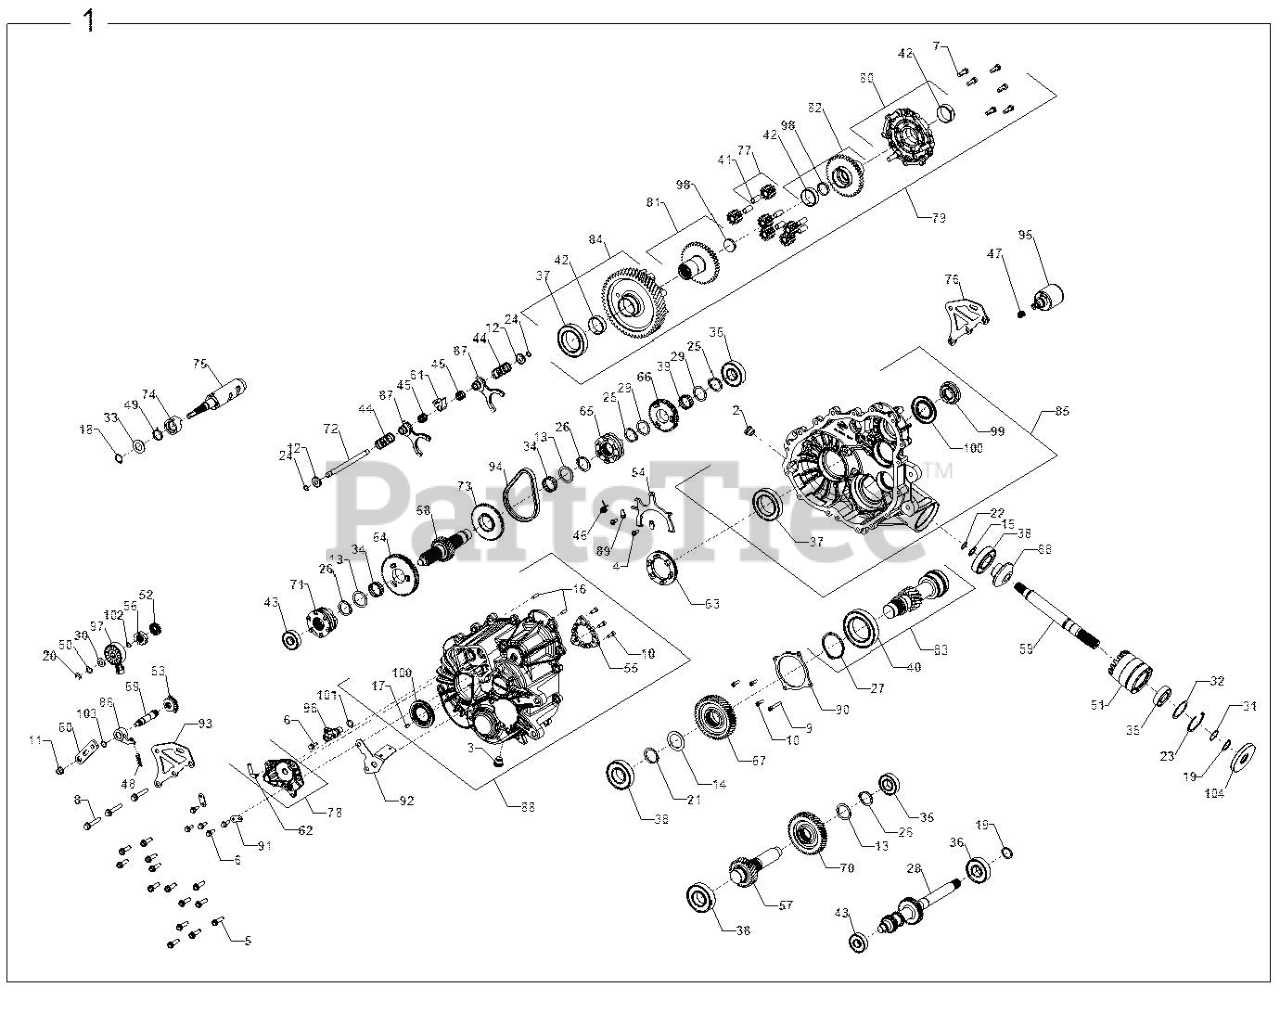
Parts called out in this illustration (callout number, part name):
1	ASM-GEARCASE,570,RGR
2	PLUG-SKT HD 1SO 6149,M18 X 1.5
3	PLUG-SOCKET HEAD W/MAG,M18X1.5
4	SCREW, TORX PAN HD M6 X 1 X 16
5	SCREW-HEXFLANGEHEAD,M8X1.25X30
7	SCREW-CAP HH,M8 X 1.25 X 20
9	SCR-M6X1.0X40,SOC/CAP(105344)
10	SCR-SCKT HD,CP,M6X1X18(105355)
11	NUT-M8X1.25,HXFLG,NYLN(110093)
12	WASHER-CUP
16	PIN, DOWEL, 6 X 20
17	SPRING-SLOTTED PIN,6MM
18	RING, RETAINING BASIC EXTERNAL
19	RING, SNAP
20	RING-RETAINING
21	RING,RETAINING
22	RING,RETAINING,EXTERNAL SHR-66
23	RING,RETAININGBASICINTRNL2.047
24	RING-RETAINING
25	RING,RETAINING
26	RING, RETAINING, EXTERNAL
27	RING, RETAINING
28	SHAFT-PINNION,INPUT,BOSS,LW
29	WASHER,THRUST
30	WASHER,THRUST,.446X.88X.025
31	SHIM 1.180 X .995
32	SHIM 2.040 OD X 1.630 ID
33	SPACER, 19.4 X 34 X 2
34	BEARING,NEEDLE
37	BEARING, BALL
38	BEARING-BALL
39	BEARING,NEEDLE
40	BEARING, BALL
41	BEARING,PLAIN,10X12X25
42	PLAIN,BEARING 40X44X15
43	BEARING, BALL
44	SPRING-COMPRESSION
45	SPRING-COMPRESSION
46	SPRING, TORSION RETURN
47	SPRING,COMPRSSN.54ODX.44IDX.05
48	SPRING, COMPRESSION DETENT
49	SPRING, TORSION
50	WASHER-SPRING,210393
51	TUBE, SNORKLE MACH
52	GEAR-SECTOR,16T
53	GEAR-SECTOR,31T-CUT TO 11T
54	SHIFT FORK (270507)
55	PARK PLATE (270509)
56	STAR, DETENT
57	SHAFT, IDLER, 29T
58	SHAFT,REVERSE,25T (285878)
59	SHAFT, OUTPUT, FRONT
60	BELLCRANK
61	COLLAR-SHIFT
62	TUBE-VENT,90-1/4" HOSE
63	DOG-ENGAGEMENT
64	GEAR-LOW,67T(352856)
65	DOG, ENGAGEMENT, 6-FACE
66	GEAR, 53T
67	GEAR, 46T, STAGE 3
68	GEAR-13T,FRONT OUTPUT(352957)
69	SHAFT, SHIFT
70	GEAR,48T STAGE 2 (353115)
71	SHIFT DOG, PARK/LOW (353357)
72	RAIL-SHIFT SHAFT(353622)
73	SPROCKET, 48T, 6-FACE
74	PARK CAM
75	DRUM, SHIFT MACH
76	WELD-REAR MOUNT BRKT
77	GEAR SUBASSEMBLY
78	SUBASSY COVER, SECTOR GEARS
79	DIFF-LOCKING (411600)
80	SUBASSY-COVER,DIFF (411601)
81	SUBASSY-GEAR,39T SIDE (411607)
82	SUBASSY-GEAR,39T SIDE (411608)
83	ASM-SUB,PINION SHAFT(411759)
84	SUBASSY-GEAR,53T (411797)
85	SUBASSY,LH CASE(411919)
86	ROLLER PAWL
87	SUBASSEMBLY, SHIFT FORK
88	SUBASSEMBLY RH COVER
89	RETAINER-FORK
90	COVER, BEARING, CENTER DRIVE
91	BRKT-MOUNT(430592)
92	BRKT-MNT,HARNESS
93	BRKT-REAR MOUNT
94	CHAIN, SILENT
95	SOLENOID
96	SENSOR-SPEED,TRANS
97	SWITCH, ROTARY 2 PIN RESISTIVE
98	PLUG,EXPANSION,1 1/4
100	SEAL-TRIPLE LIP,VITON,40X70X7
101	O-RING, -113
104	SEAL-TRIPLE LIP 25X80X10
